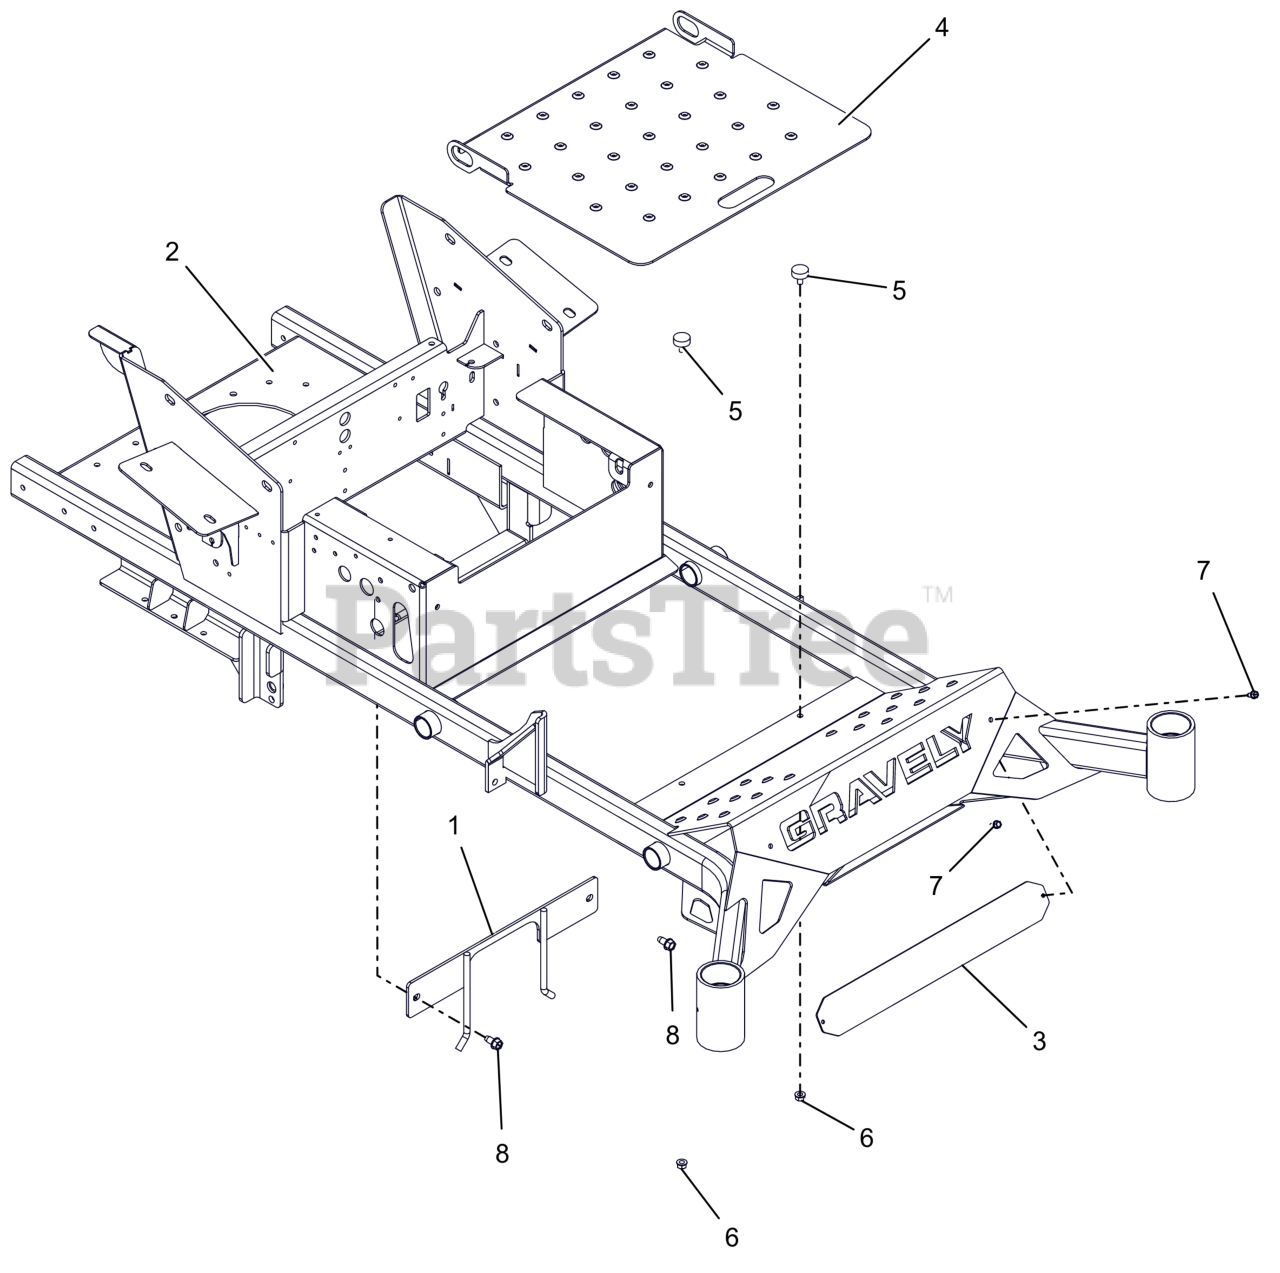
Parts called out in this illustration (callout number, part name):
1	PTO BELT FINGER WLDMT - BLK
2	PT/100 60" FRAME W/SAFETY DECL
3	BUMPER LOGO BACKING PLATE -BLK
4	PT/100 FOOT PLT W/SAFETY DECAL
5	BUMPER, RUBBER
6	NUT,SPNLK-FLG .31-18 G5 ZCC
7	SCR-TAP .25-20X.50 HWH ZCC
8	SCR,TAP .375-16X.75 HWH TR ZCC
